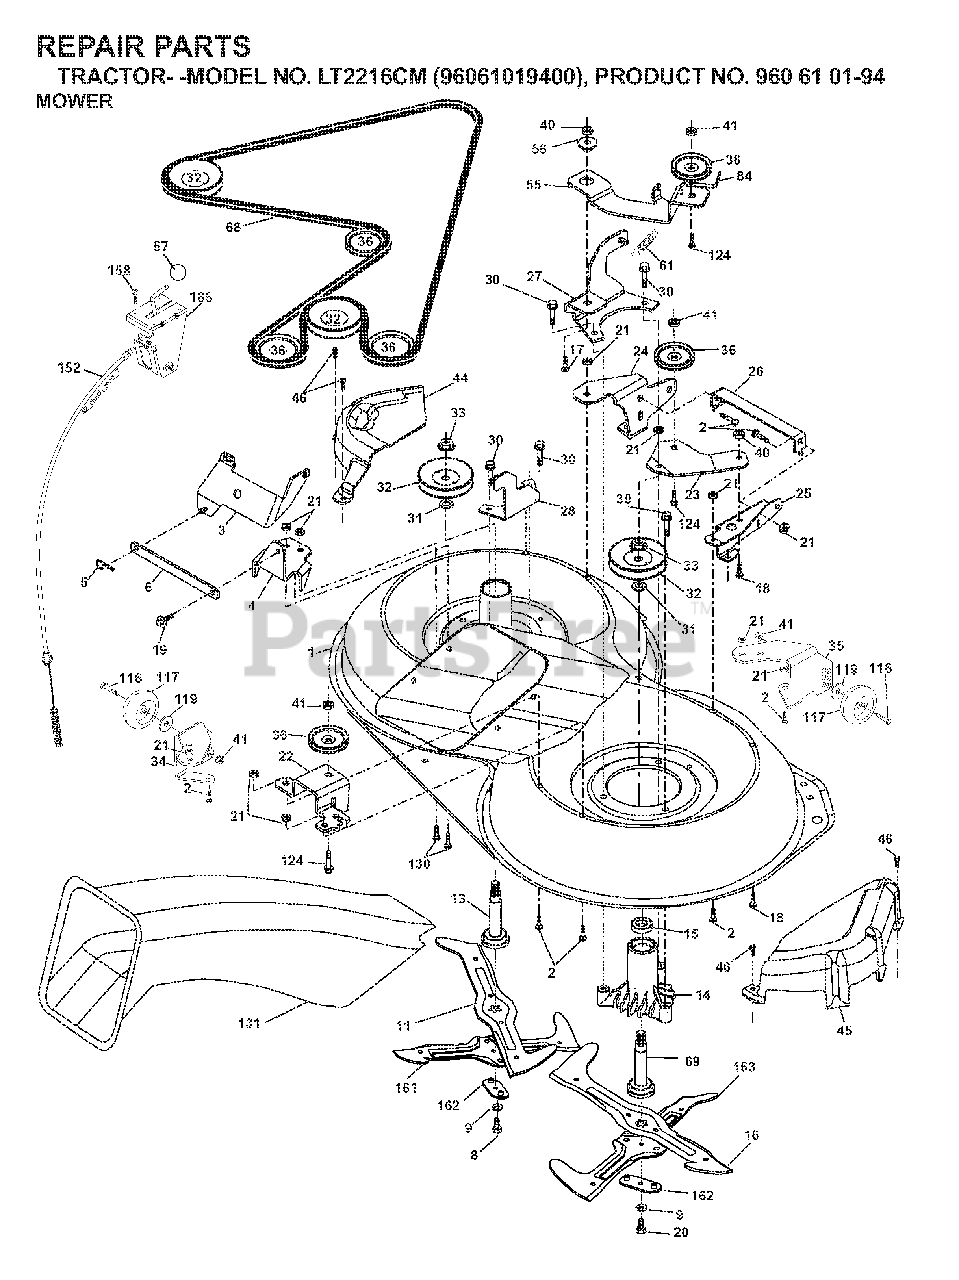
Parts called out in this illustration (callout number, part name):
2	BOLT
3	BRACKET
5	RETAINER-SPRNG RB
6	BAR SWAY
9	LOCKWASHER
10	WASHER.BLADE
13	SHAFT ASM VENT
14	HSG MANDREL
17	BOLT.3/8-14X1.25
19	BOLT SHD 5/16-18
21	LOCKNUT
24	BRACKET
25	BRACKET
28	BRACKET
30	SCREW, WASHER HEAD
31	WASHER.SPACER.MANDREL
32	PULLEY MANDREL
33	NUT.FLANGE.LOCK.TOP
36	PULLEY.IDLER.4.25
40	LOCKNUT
41	NUT LOCK FLG 3/8-16 UNC
45	MANDREL COVER
46	SCREW.1/4-20X5/8
56	SPACER.RETAINER.MOWER
67	KNOB T (3/8 HOLE)
69	SHAFT.ASM.W/LWR.BRG.RH.THREAD
84	KEEPER, BELT IDLER
116	BOLT.SHOULDER.3/8-16X3-5/8
117	WHEEL. GUAGE RALLY
118	NUT LOCK FLG 3/8-16 UNC
124	BOLT.3/8-16X1.50
131	CHUTE BAGGER
158	SCREW
185	HEAD ASM. CABLE CLUTCH
